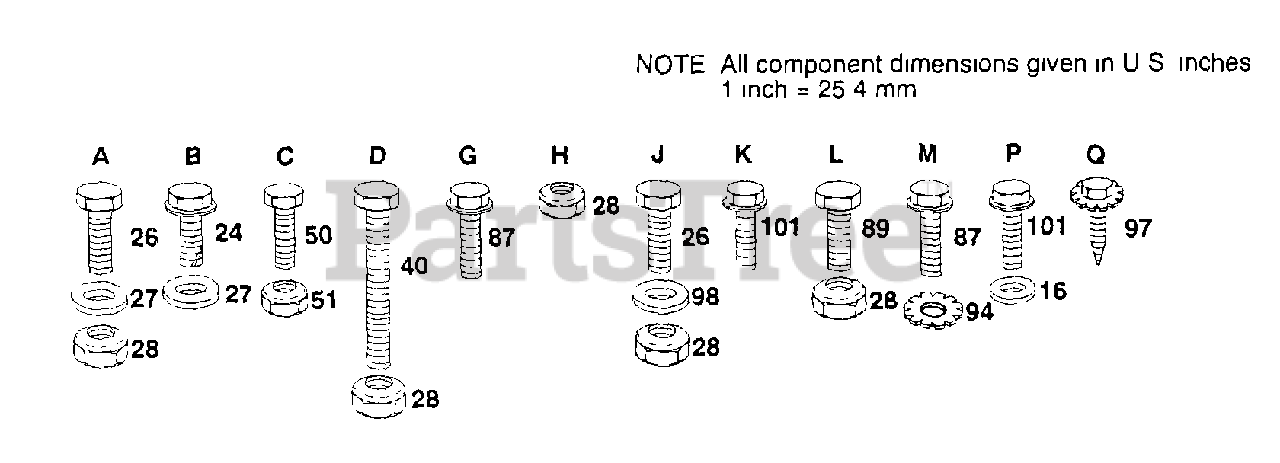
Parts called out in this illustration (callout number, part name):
16	WASHER
24	SCREW
26	BOLT
27	WASHER
40	BOLT
50	BOLT
87	SCREW
94	LOCKWASHER
98	WASHER
101	SCREW
